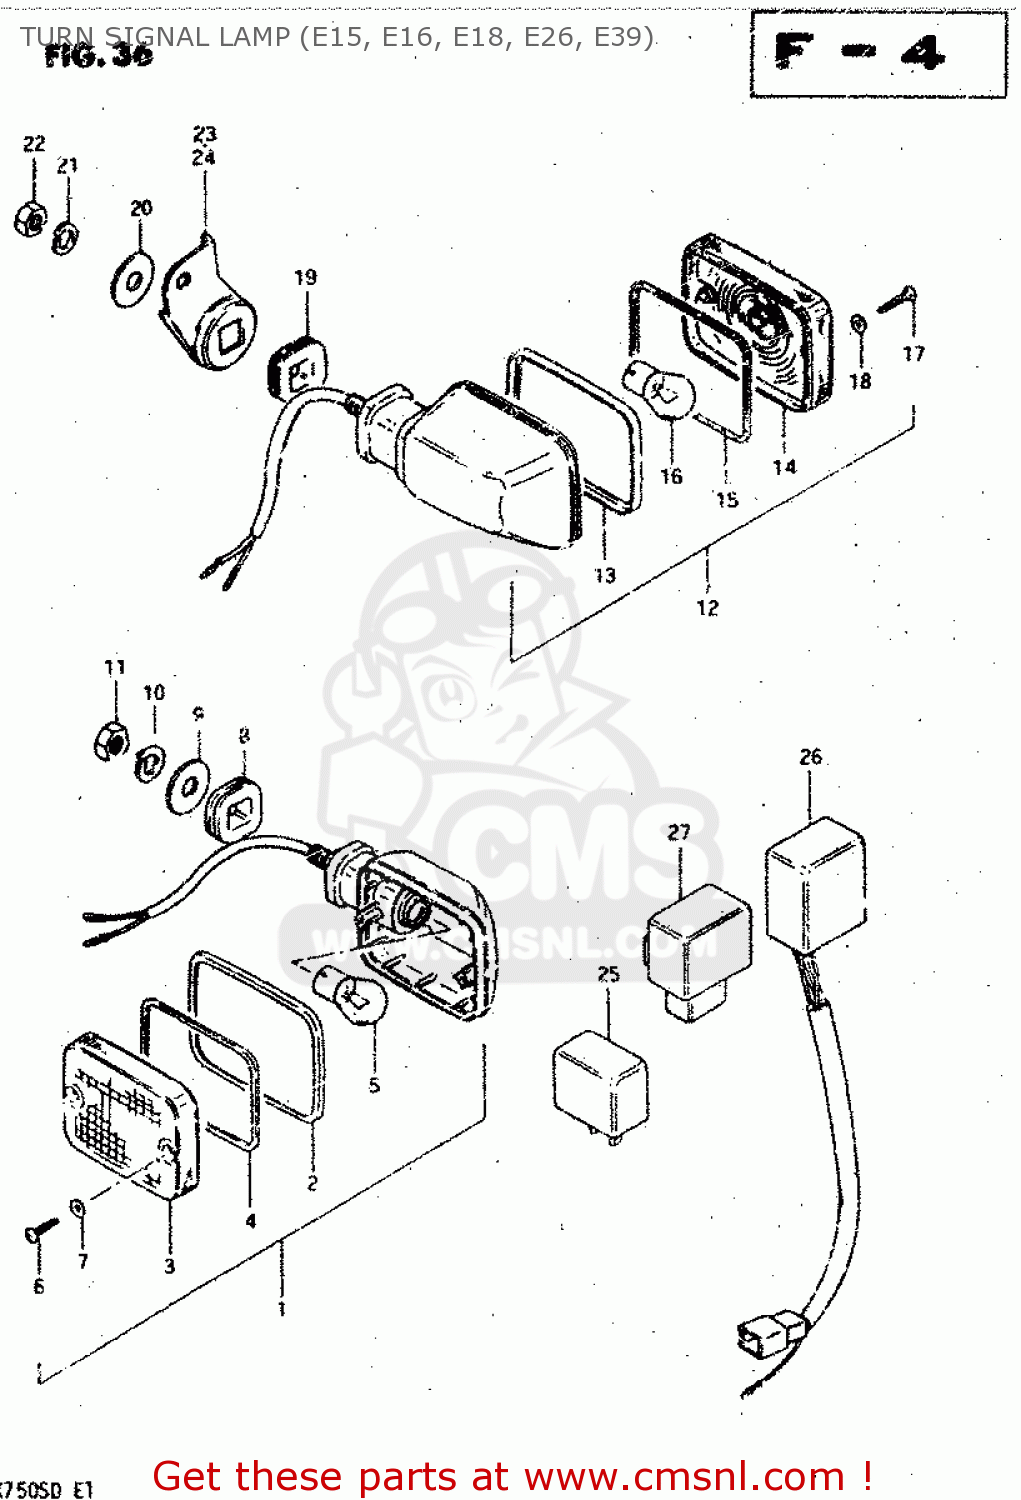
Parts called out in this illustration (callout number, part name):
1	LAMP ASSY,FR T
2	RIM
3	LENS
4	GASKET (NAS)
5	BULB 12V 21W
6	SCREW
7	GASKET (NAS)
8	CUSHION
9	WASHER (10.5X30X2.3)
10	LOCK WASHER
11	NUT
12	LAMP ASSY,RR T
13	RIM
14	LENS
15	GASKET (NAS)
16	BULB 12V 21W
17	SCREW
18	GASKET (NAS)
19	CUSHION
20	WASHER (10.5X30X2.3)
21	LOCK WASHER
22	NUT
23	BRACKET,RR TURNSIGNAL LAMP,R
24	BRACKET,RR TURNSIGNAL LAMP,L
25	RELAY ASSY,TURNSIGNAL
26	UNIT,TURN SIGNAL CONTROL
27	UNIT,TURN SIGNAL CONTROL
